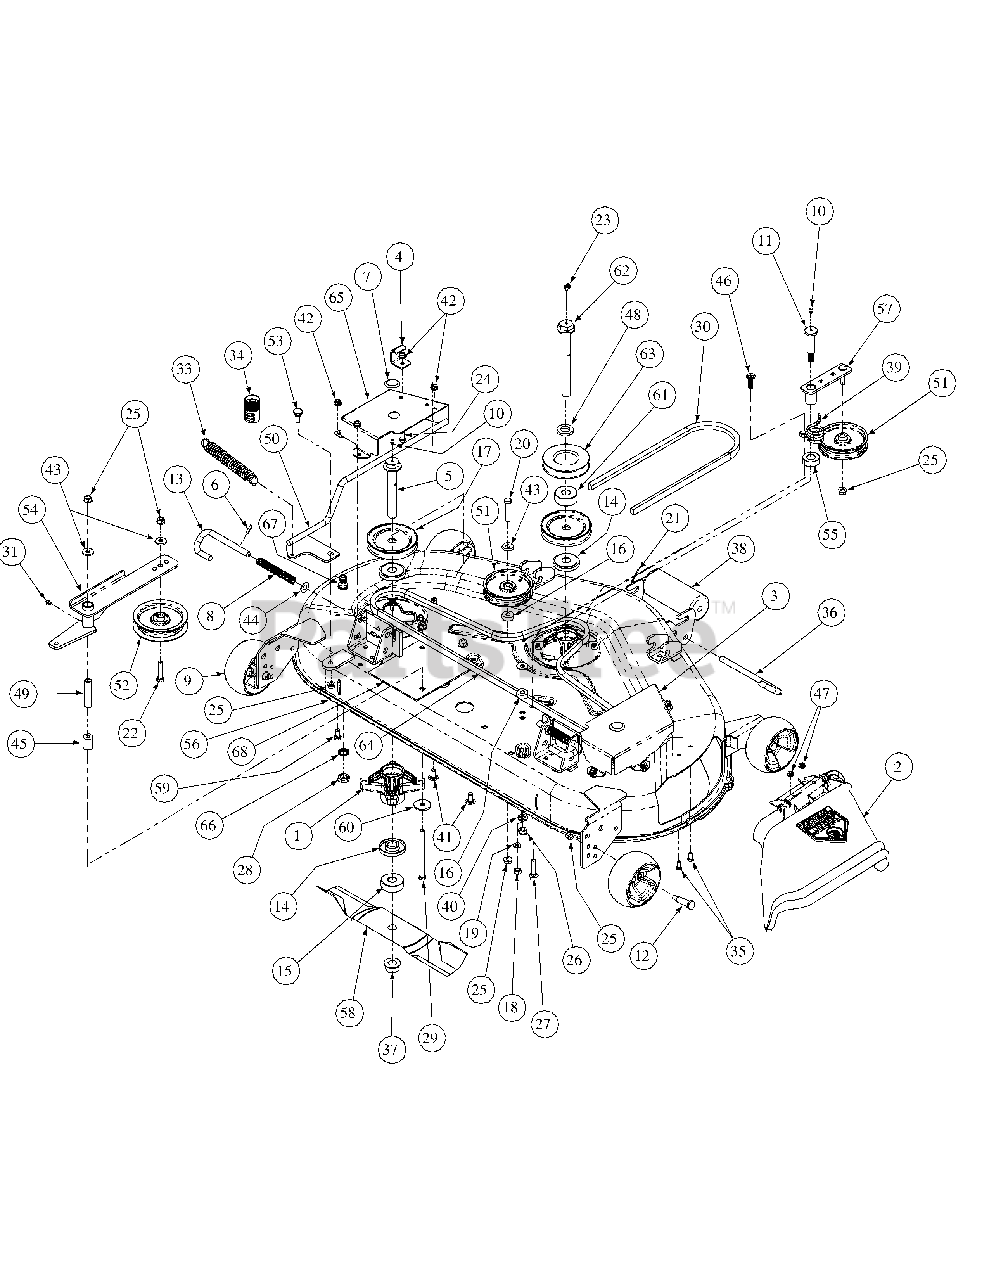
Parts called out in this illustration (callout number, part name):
1	Spindle Assembly
2	Chute Assembly
3	Belt Cover Right Hand
4	Tension Rod Stop Bracket
5	Spindle Bolt 3/4-16 x 5.37
7	Button Plug
8	Compression Spring .63 OD x 6.3
9	Deck Wheel, 5.00 Dia.
10	Grease Fitting
11	Shoulder Screw .68 x 2.11
12	Shoulder Screw .498 x 1.53
13	Support Pin
14	Spindle Spacer
15	Blade Spacer
16	Spacer .406 ID x 1.0 OD
17	Pulley
18	Hex Nut 3/8-16
19	Lock Washer, 3/8
20	Hex Cap Screw 3/8-16 x 2.00
21	Cotter Pin .125 Dia x 1.0
22	Capscrew, 3/8-16 x 1-3/4
23	Grease Fitting, 1/4-28, 90 degree
24	Hex Cap Screw 5/16-18 x .75
25	Hex Nut, 3/8-16, Flange Lock
26	Nut 7/16-14, Nylock
27	Carriage Bolt 3/8-16 x 1.50
28	Hex Nut, M16-1.5
29	Hex Cap Screw 3/8-16 x 5.00
30	V-Belt, B-Section
31	Grease Fitting, 1/4-28 x 3/16
32	Idler Washer
33	Extension Spring, 1.0 OD x 5.00
34	Water Nozzle Adaptor
35	Hex Cap Screw 1/4-20 x .620
36	Roller Pin 1/2 x 7.31
37	Nut, 3/4-16, Hex Flange
38	Front Roller
39	Idler Spring
40	Flat Washer, .469 ID x .875 OD x .105
41	Carriage Bolt, 3/8-16 x .75
42	Lock Nut 5/16-18 Hex Flange
43	Flat Washer, .406 ID x 1.0 OD x .105
44	Flat Washer .508 ID x 1.0 OD
45	Spacer, .39 ID x .875 OD x 1.100
46	Carraige Screw, 3/8-16 x 1.25
47	Nut, 1/4-20, hexflange Lock
48	Spacer .812 ID x .218
49	Spacer, .39 ID x .625 OD x 2.75
50	Deck Handle Weldment
51	Flat Pulley
52	Idler Pulley, 4.06 OD
53	Shoulder Screw, .50 x .27 Lg., 3/8-16
54	Idler Arm Assembly, Top
55	Spacer .760 ID x 1.5 OD
56	Deck Assembly 44"
57	Idler Arm Assembly
58	Blade
59	Self Tapping Screw 5/16-18 x .750
60	Washer, 5/16-18
61	Spacer .760 ID x 2.00 OD x 0.790
62	Spindle Bolt 3/4-16 x 7.155
63	V-Pulley 4.25 OD Casting
64	V-Belt, A-Section
65	Belt Cover Left Hand
66	Lock Washer, 17 x 23.8 x 1.95
67	Deck Water Nozzle
68	Deck Plate
